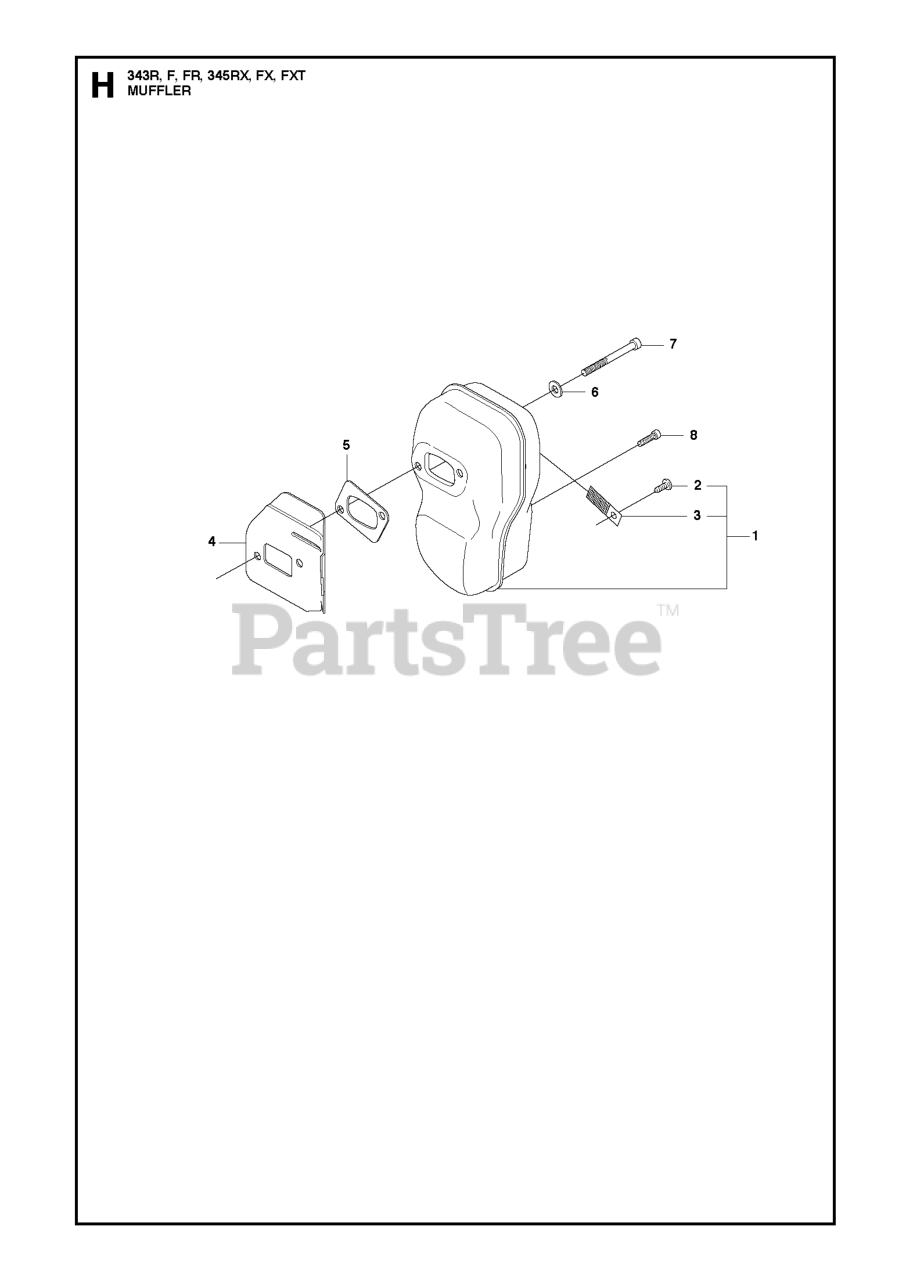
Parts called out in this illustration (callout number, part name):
1	MUFFLER
4	SCREW IHSCFM
6	DOUBLE WASHER
